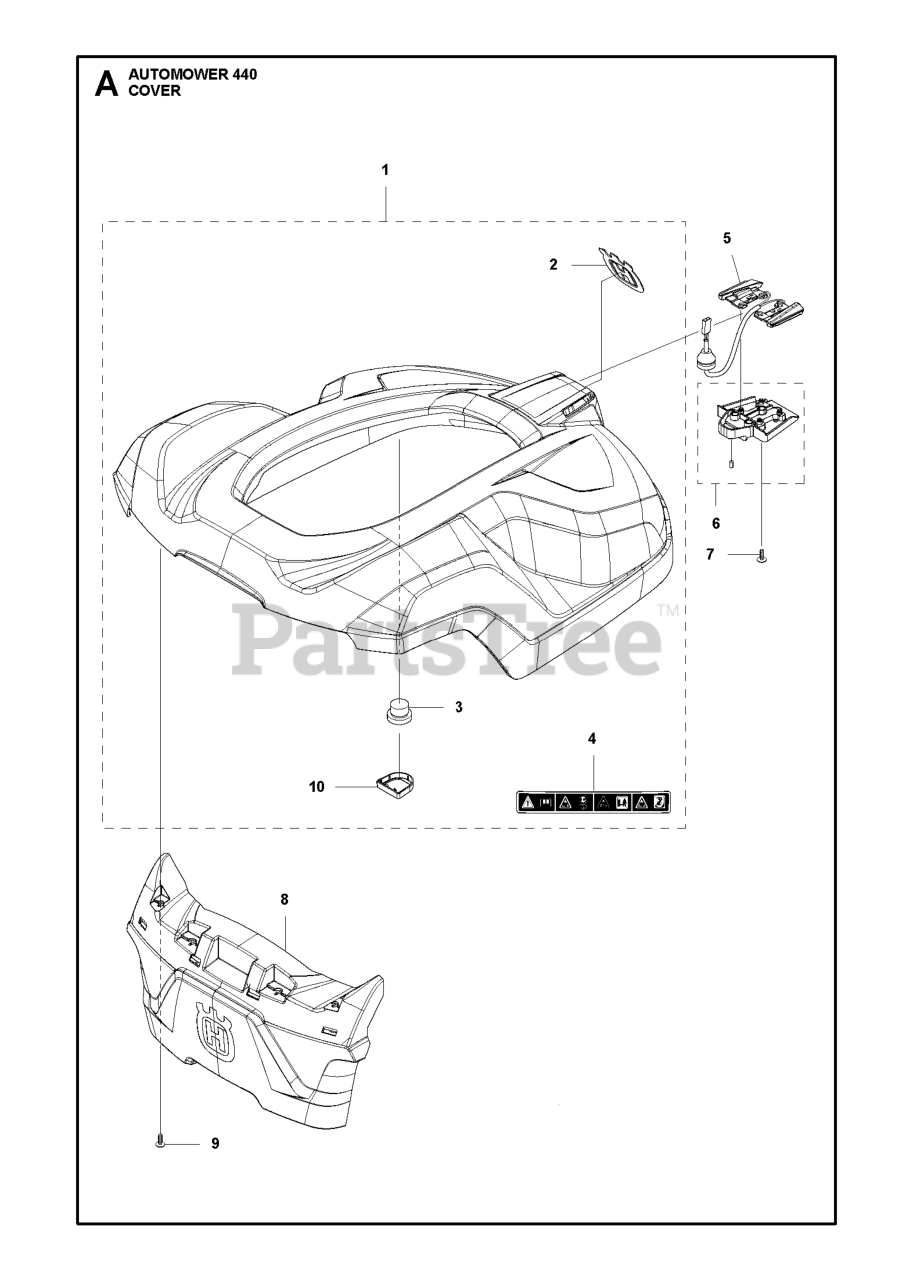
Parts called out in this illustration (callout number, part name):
2	DECAL HUSQVARNA CROWN HEIGHT 5
3	CAP SNAPLOC
4	LABEL WARNING P15
5	CABLE ASSY CHARGING PLATE
6	HOLDER ASSY MAGNET
7	SCREW 14MM
8	BUMPER REAR
9	SCREW ITXPANT
